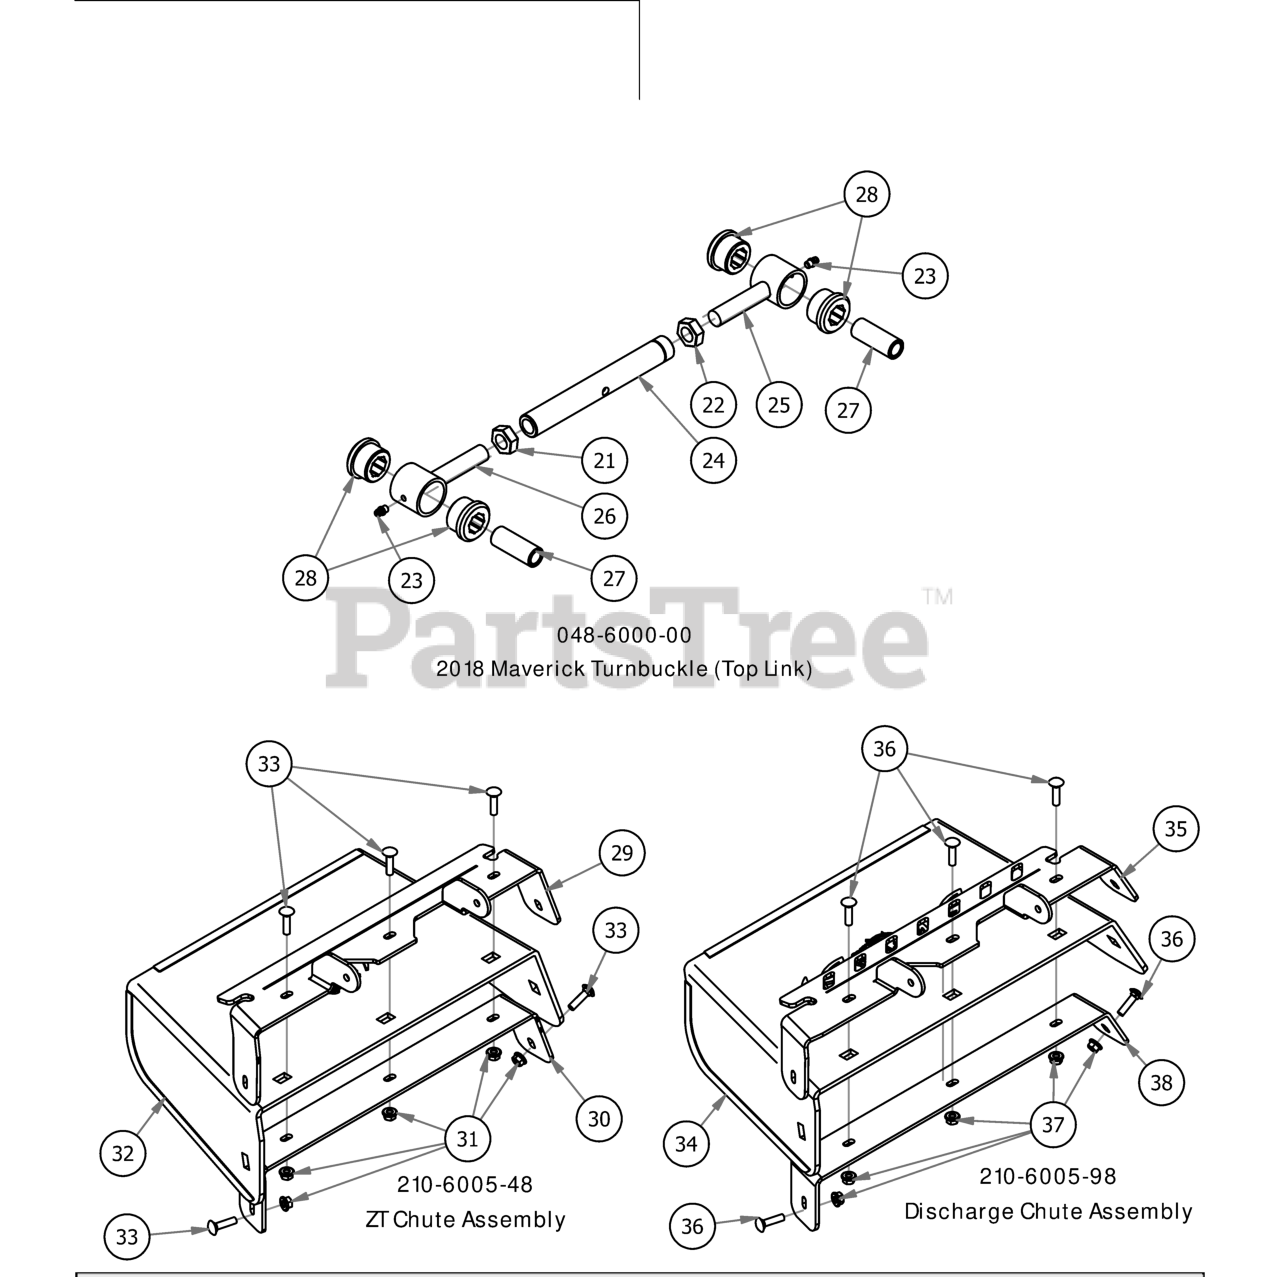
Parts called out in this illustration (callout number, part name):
21	NUT, 5/8-18
22	NUT, 5/8-18LH
23	1/4-28 Grease Fitting
24	2018 Maverick Toplink Body
25	2018 Maverick Bushing Retainer Left-Handed
26	2018 Maverick Bushing Retainer Right-Handed
27	2018 Maverick Bushing Sleeve
28	2018 Maverick Bushing
29	Discharge Upper Chute Bracket
30	Discharge Lower Chute Bracket
31	5/16-18 NYLON INSERT FLANGE LOCKNUT ZINC
32	Rubber Discharge Chute
33	5/16-18 X 1-1/4 CARRIAGE BOLT ZINC
34	Rubber Discharge Chute
35	60" Discharge Chute Upper Hanger
36	5/16-18 X 1-1/4 CARRIAGE BOLT ZINC
37	5/16-18 NYLON INSERT FLANGE LOCKNUT ZINC
38	60" Discharge Lower Bracket
